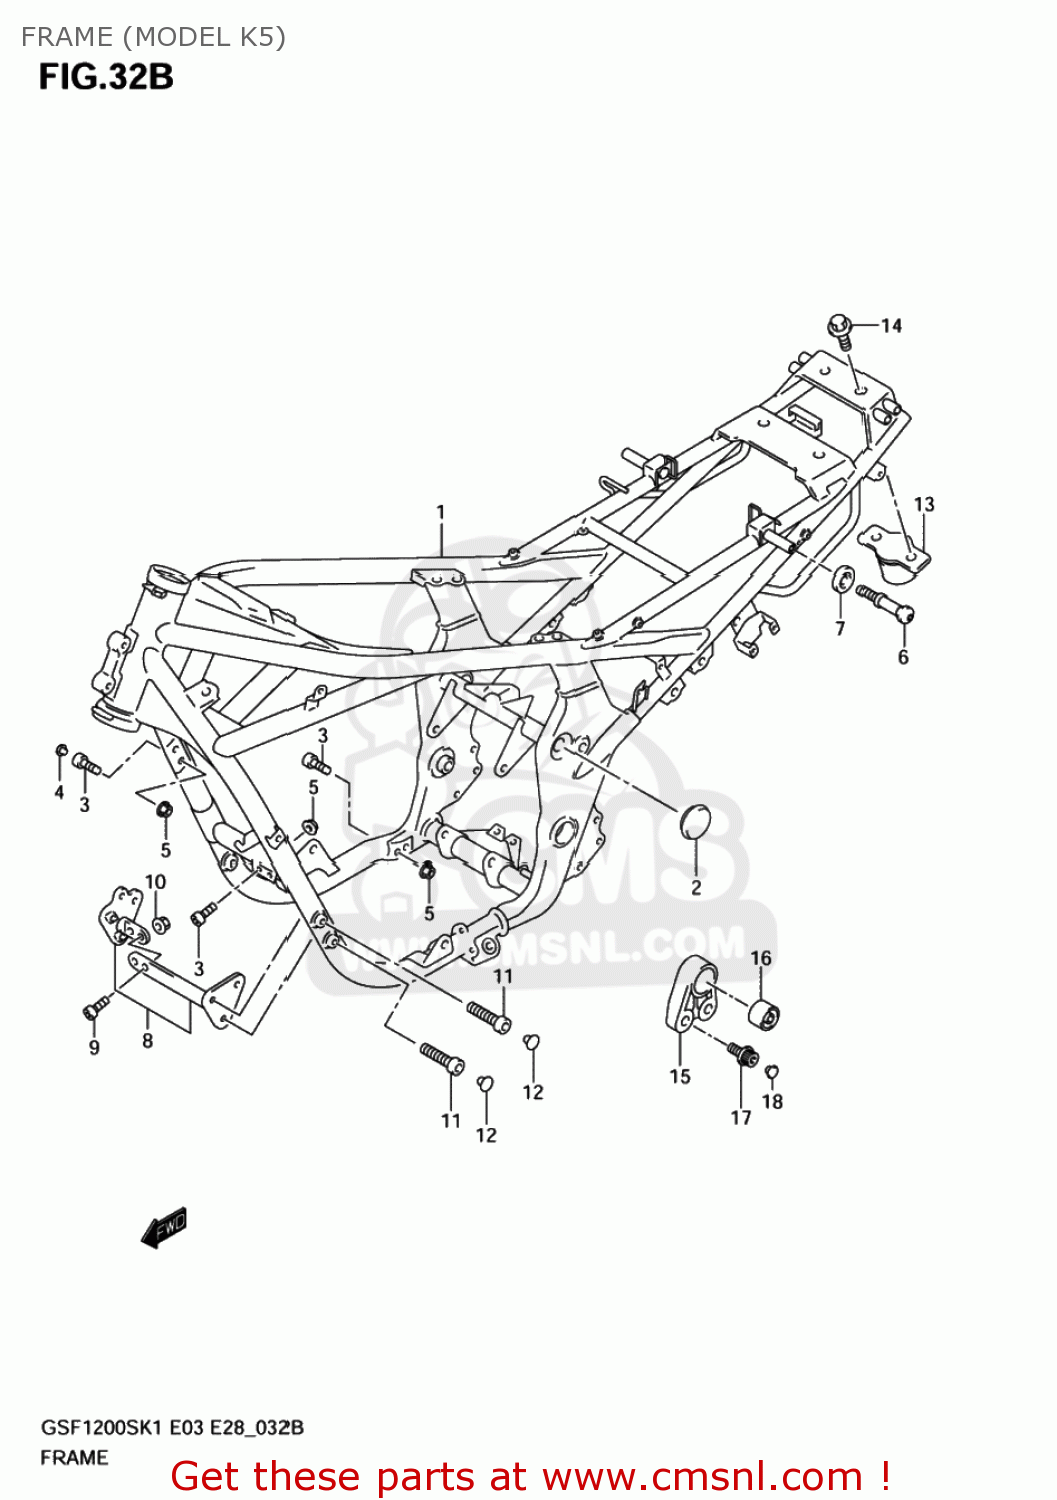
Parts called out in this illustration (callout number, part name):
1	FRAME(BLACK)
2	CAP,FRAME BODY
3	BOLT(10X37)
4	CAP(OD:12)
5	NUT
6	HOOK,SEAT RAIL
7	WASHER,HOOK
8	PLAAT
9	BOLT
10	NUT
11	BOLT(8X50)
12	CAP(OD:12)
13	DAMPER,FRAME RR
14	BOLT
15	BRACKET,ENGINE MOUNTING NO.2
16	BUSH,ENG MOUNTING NO.2
17	BOLT(8X28)
18	CAP(OD:10)
